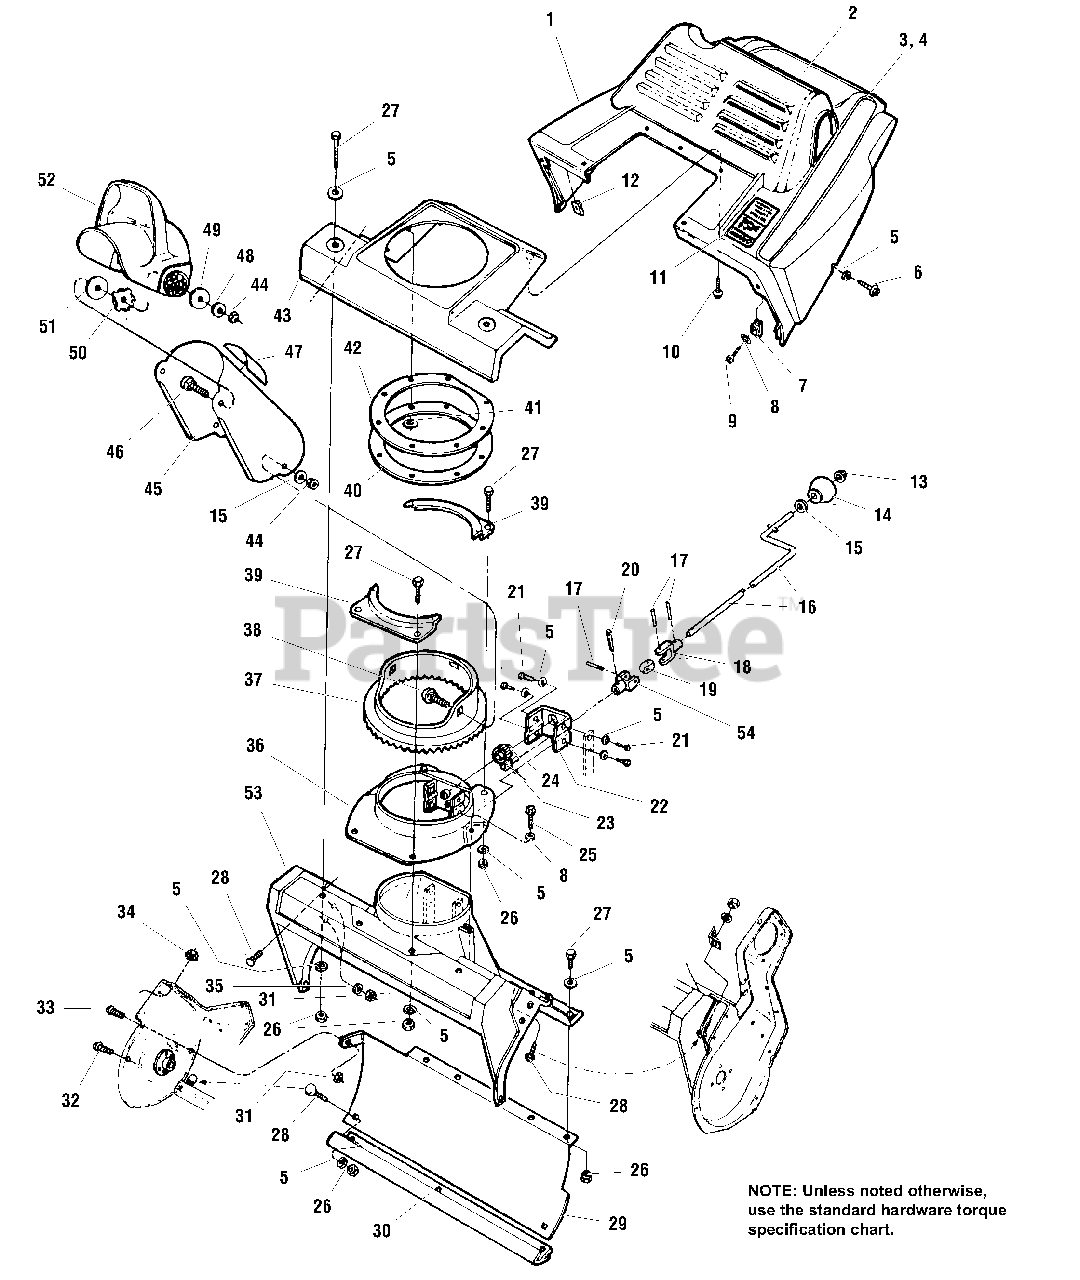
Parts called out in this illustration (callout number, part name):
1	COVER, Engine
2	DECAL, Console (Electric Start)
3	DECAL, Logo RH
4	DECAL, Logo LH
5	WASHER, Flat, 1/4
6	SCREW, Thread Forming, #10 x 5/8
7	CLIP, #10
8	WASHER, Flat #10
9	SCREW, Hex, #10-16 x 1-1/2
10	SCREW, Thread Forming, #10 x 5/8
11	DECAL, Danger, Auger
13	PAL NUT, 5/16
14	KNOB, Chute Rotate Handle
15	WASHER, Flat, 5/16
16	HANDLE, Chute Rotate
17	PIN, Spiral, 5/32 x 1
18	CLEVIS, U-joint
19	CONNECTOR, U-joint
20	PIN, Cotter, 1/8 Dia.
21	SCREW, Hex, 1/4 - 20 x 5/8
22	BRACKET, Gear
23	DRIVE, Gear
24	GEAR, Idler
25	SCREW, Plastite, #12-14 x 1
26	NUT, Nylock, 1/4-20
27	SCREW, Hex, 1/4-20 x 3/4
28	CARRIAGE BOLT, 1/4-20 x 3/4
30	SCRAPER, Bar
31	NUT, Flange, 1/4-20
32	SCREW, Phillips, 10-24 x 5/8
33	SCREW, Phillips, #10-24 x 7/16
34	NUT, Keps, 1/4 - 20
35	WASHER, Flat
36	PLATE, Chute Base
37	BASE, Chute
38	CARRIAGE BOLT, 5/16-18 x 5/8
40	RETAINER, Gasket
41	NUT, Push On
42	GASKET, Chute
43	COWLING, Transition
44	NUT, Nylock, 5/16-18
45	CHUTE, Discharge
46	CARRIAGE BOLT, 5/16-18 x 1
47	DECAL, Danger
48	WASHER, Belleville
49	WASHER, Flat 5/16
50	WASHER, Octagon
51	WASHER, Flat Rubber
52	DEFLECTOR, Chute
53	HOUSING, Auger
54	CLEVIS, U-Joint
